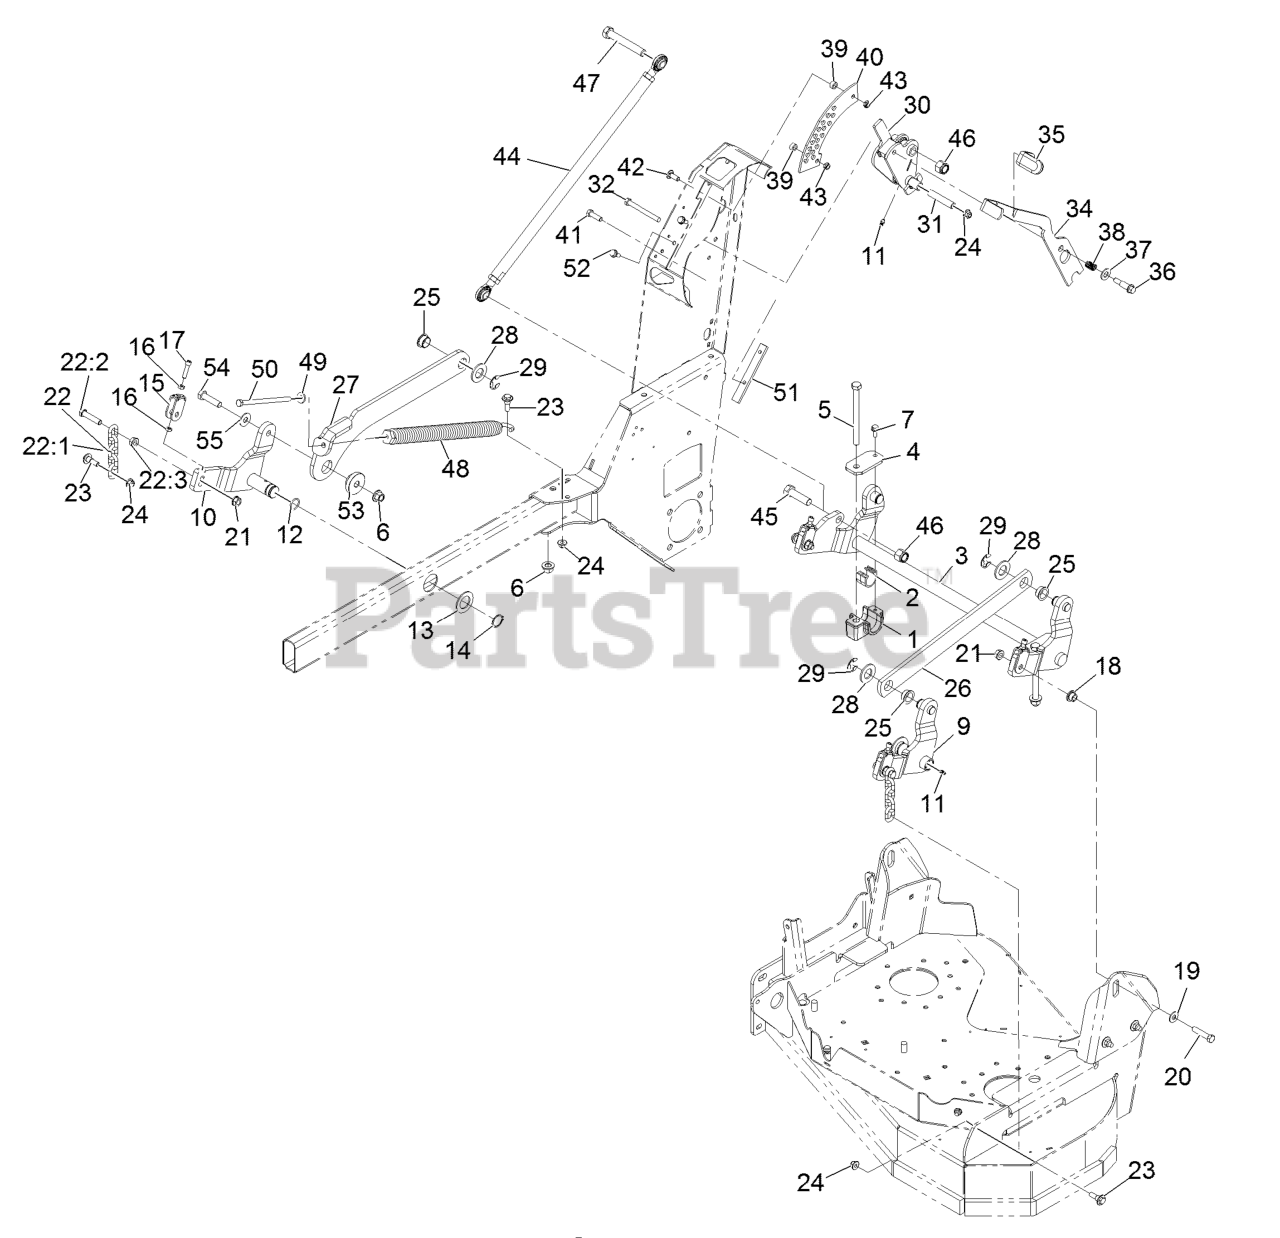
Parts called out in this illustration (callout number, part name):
1	SUPPORT-BEARING
2	BEARING-CROSS SHAFT, FRON
3	REAR CROSSSHAFT ASM
4	COVER-BEARING SUPPORT
5	SCREW-HH
6	Nut-Lock 1/2-13
7	SCREW-HHF
9	DECKLIFT ARM ASM-LH
10	DECKLIFT ARM ASM-RH
11	FITTING-GREASE
12	O RING
14	RING-RETAINING
15	YOKE-ADJUST, DECK
16	NUT-JAM
17	SCREW-HSH
18	BUSHING-FLANGED
19	WASHER-FLAT
20	SCREW-HH
22	DECK LIFT CHAIN ASM
22:1	CHAIN-LIFT, DECK
22:2	SCREW-HH
23	SCREW-SHOULDER, HHF
24	NUT-HF, NI
25	BEARING-FLANGE
26	LINK-DECKLIFT, LH
27	LINK-DECKLIFT, RH
28	WASHER-FLAT
29	RING-RETAINING, EXT
30	ASM-HOC HANDLE
31	BEARING-HOC PIVOT
32	SCREW-HH
34	LEVER-HOC
35	GRIP-LEVER
36	SCREW-SHOULDER
37	WASHER-FLAT
39	SPACER
40	BRACKET-HOC
41	SCREW-HH
42	SCREW-CARR
44	HOC LINK ASM
45	SCREW-HH
46	NUT-LOCK, NI
47	SCREW-HH
48	SPRING-EXTENSION
49	WASHER-BELLEVILLE
50	BOLT-TAP, HH
51	SKID-HANDLE, LIFT
52	SCREW-THD ROLL, HWH
53	BUSHING-FLANGED
54	SCREW-HH
55	WASHER-FLAT
